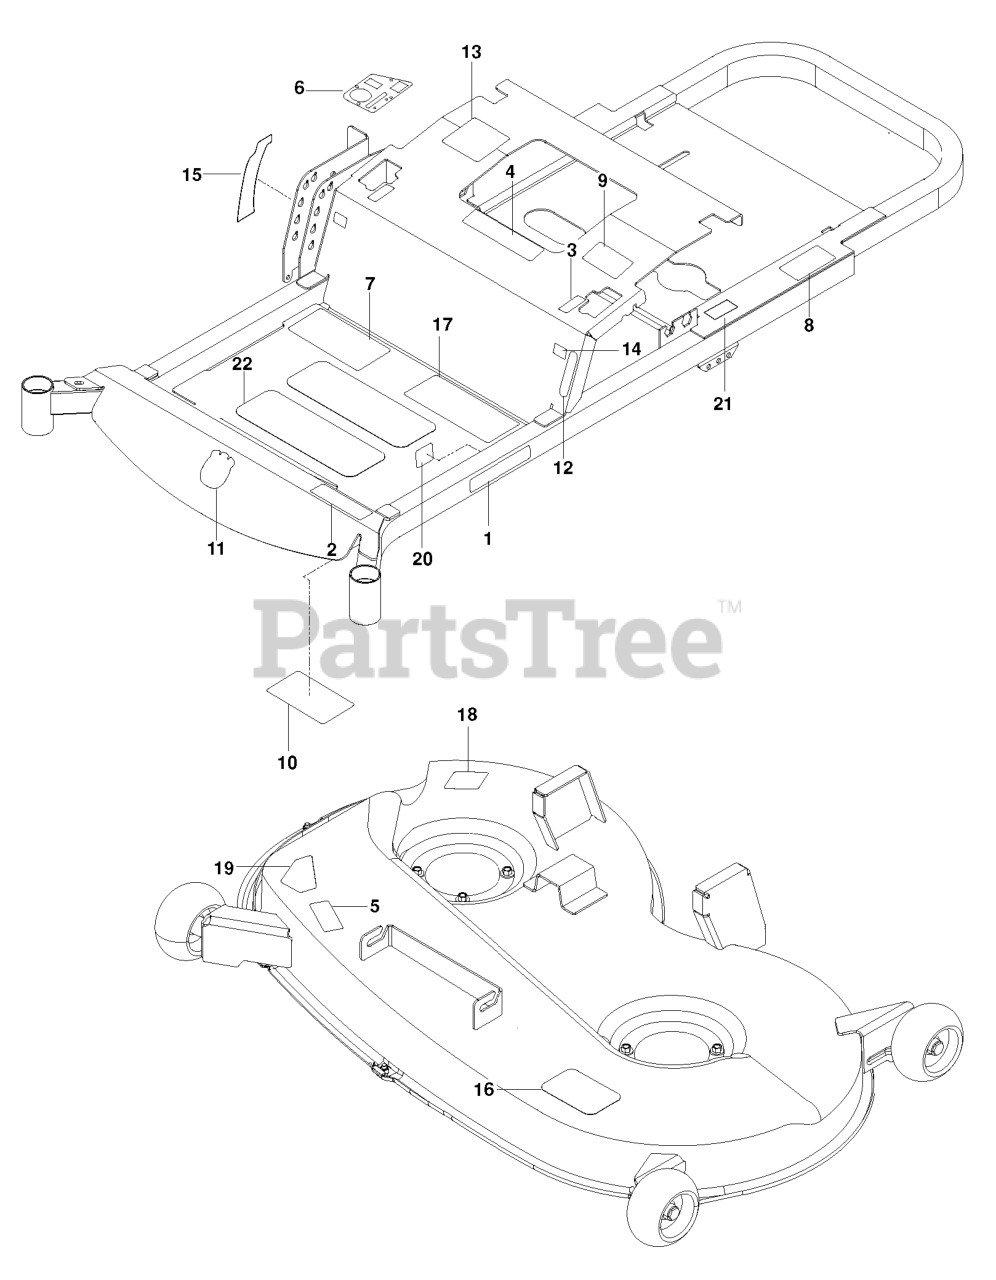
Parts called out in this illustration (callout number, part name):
1	RP.DECAL.BADGE.170MM.TEXTLOGO
3	DECAL, MOTION CONTROL
4	EURO DECAL-BATTERY WARNIN6
5	DECAL, EURO SEVERING
6	DECAL.ZTR.CONTROL.PANEL.HUSQV
7	DECAL.ZTR.STRTNGINS.SMARTIGNIT
8	DECAL, DO NOT TOW
9	DECAL, EXITING MOWER
10	DECAL, SERVICE
11	DECAL.AUGER.HUSQ.CROWN.SNOW
12	DECAL, PARK BRAKE
13	DECAL, CUSTOMER RESPNSIBILITY
14	DECAL, F.S.T.
15	DECAL, DECK HEIGHT, HUSQ
16	DECAL, BELT ROUTING
17	DECAL.ZTR.WARNING.SMARTIGNITIN
18	DECAL.DECK.6MIL./DEF.SHLD.WARN
19	DECAL, CPSC
20	DECAL, ECM, AUSTRALIA
21	DECAL.80.DBA.AUSTRALIA
22	ANTI-SKID PAD
